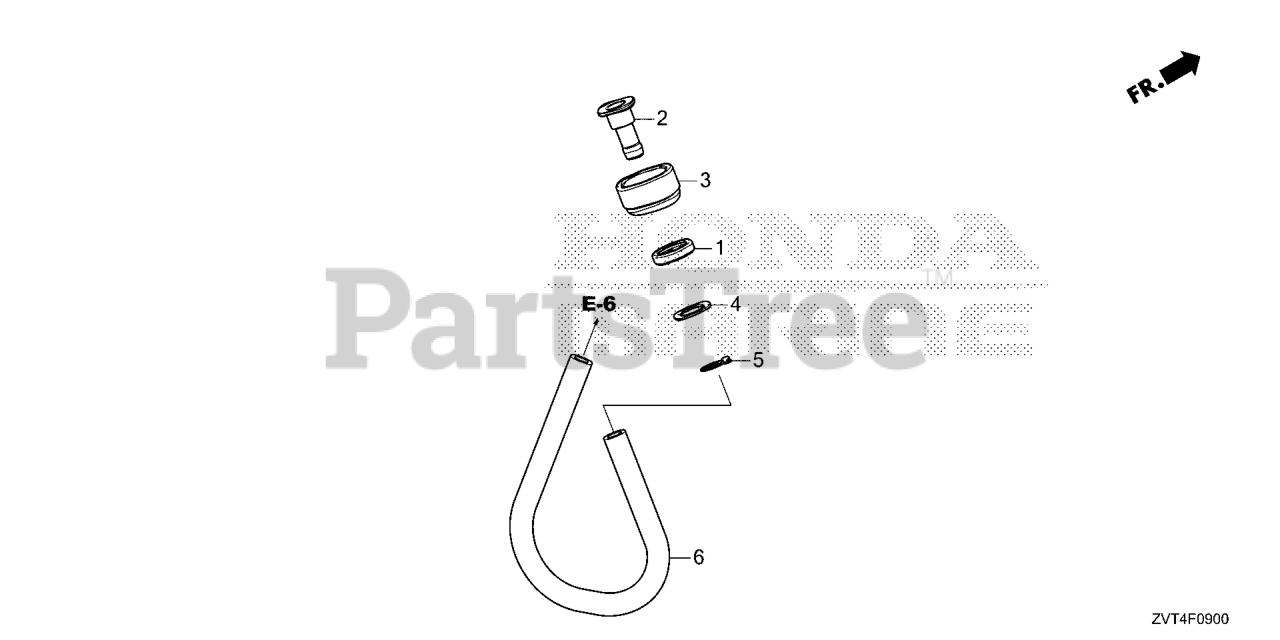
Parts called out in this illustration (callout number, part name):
1	NUT, WATER MOUTH
2	JOINT, WATER HOSE
3	SEAT, WATER MOUTH
4	SEAT, WATER JOINT
5	CLIP B1, TUBE
6	BULK HOSE, FUEL (8X1000) (95001-80001-(95001-80001-60M)
